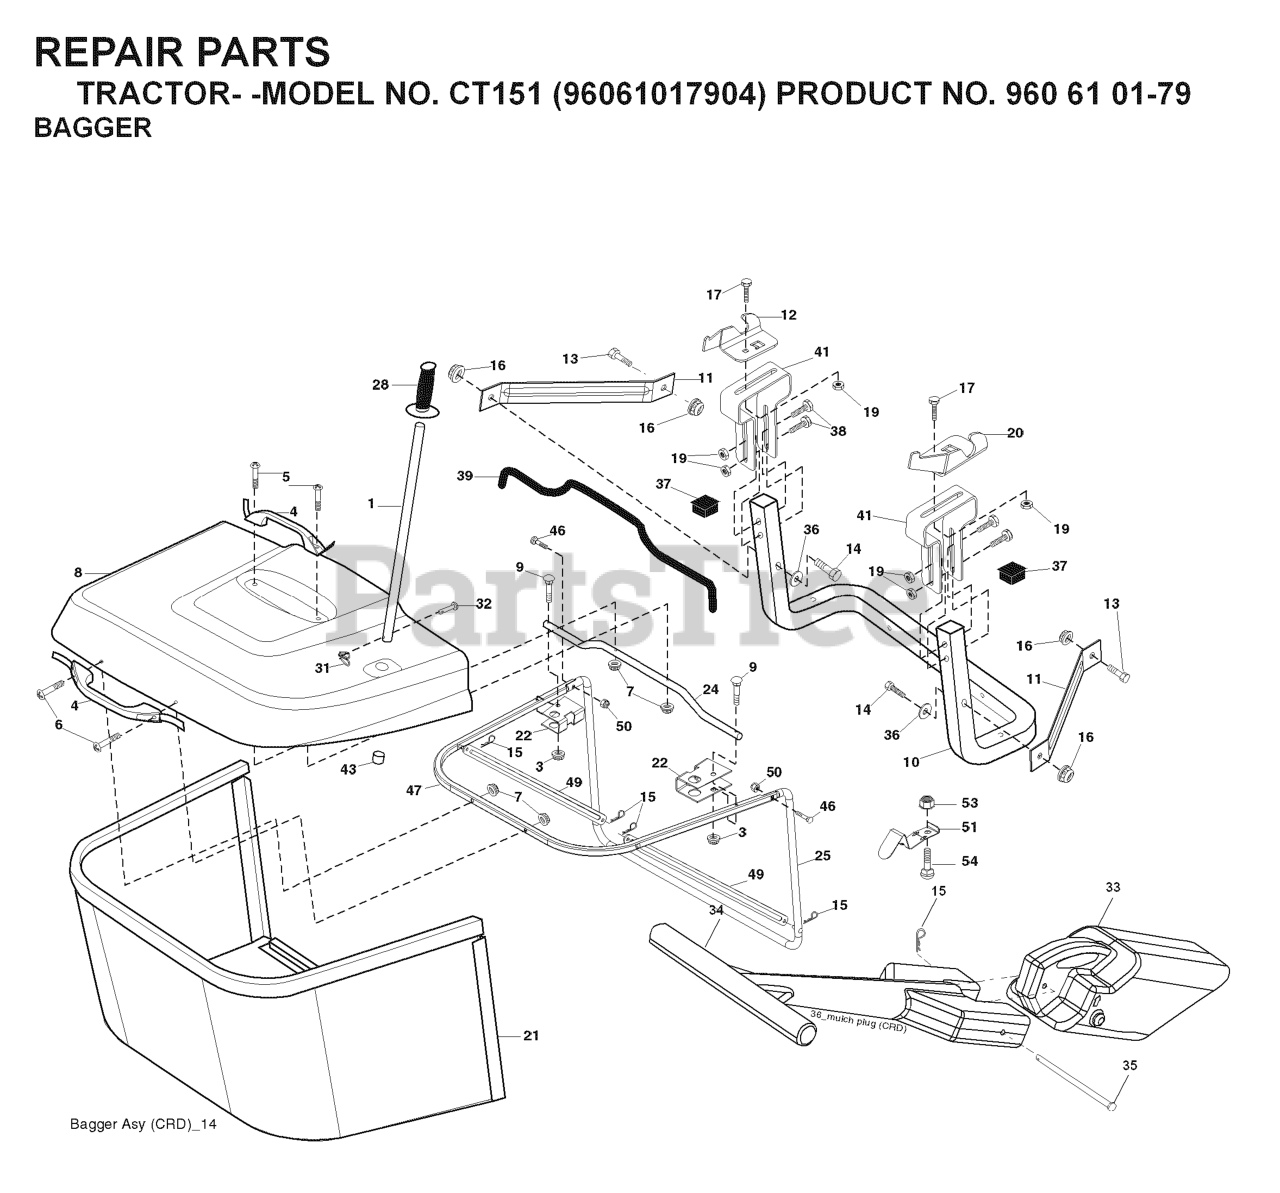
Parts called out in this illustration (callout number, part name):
1	TUBE HANDLE
3	NUT T
4	HANDLE.BAGGER.W/LVRS.BLK.CRD
5	SCREW.PAN.HEAD
6	REPL BY 532 75 00-29
8	COVER.PNT.BGR.CRD.WSLOTS.MS668
9	Bolt Carriage 1/4-20 x 2.25d x Gr.5
10	TUBE
11	BRACKET.SUPPORT.UPPER.BAG.CRD
12	BRKT PIVOT
14	BOLT-HEX EAK
15	RETAINER-SPRNG RB
16	NUT LOCK FLG 3/8-16 UNC
17	RP BOLT 5/16-18 X3/4 ZN/YEL GR
19	NUT LOCK HEX FLANGE 5/16-18
20	BRKT.PIVOT.RH.CRD
21	BAGGER.ASM.CRD.2007
22	BRKT.SIDE.BAG.CRD
24	TUBE.PIVOT.BAG.CRD.BLACK
25	PIPE
28	GRIP.HANDLE.BLACK
31	RETAINER CLIP
32	RIVET,DRILLED
33	PLUG.MULCHER.92 CRD
34	HANDLE.MULCHER.92.CRD (2 2)
36	WASHER
37	Plug Support Bagger CRD
38	BOLT.5/16-18X2.5
39	SEAL.TRIM.37'
41	BRKT.VERT.ADJ.BAGGER.CRD
43	PLUG, TUBING END
46	BOLT.CARRIAGE.5/16-18
47	PIPE
49	ROD
50	NUT.71038.31-18.HEX.NYLOCK
51	LATCH
53	NUT
54	BOLT
